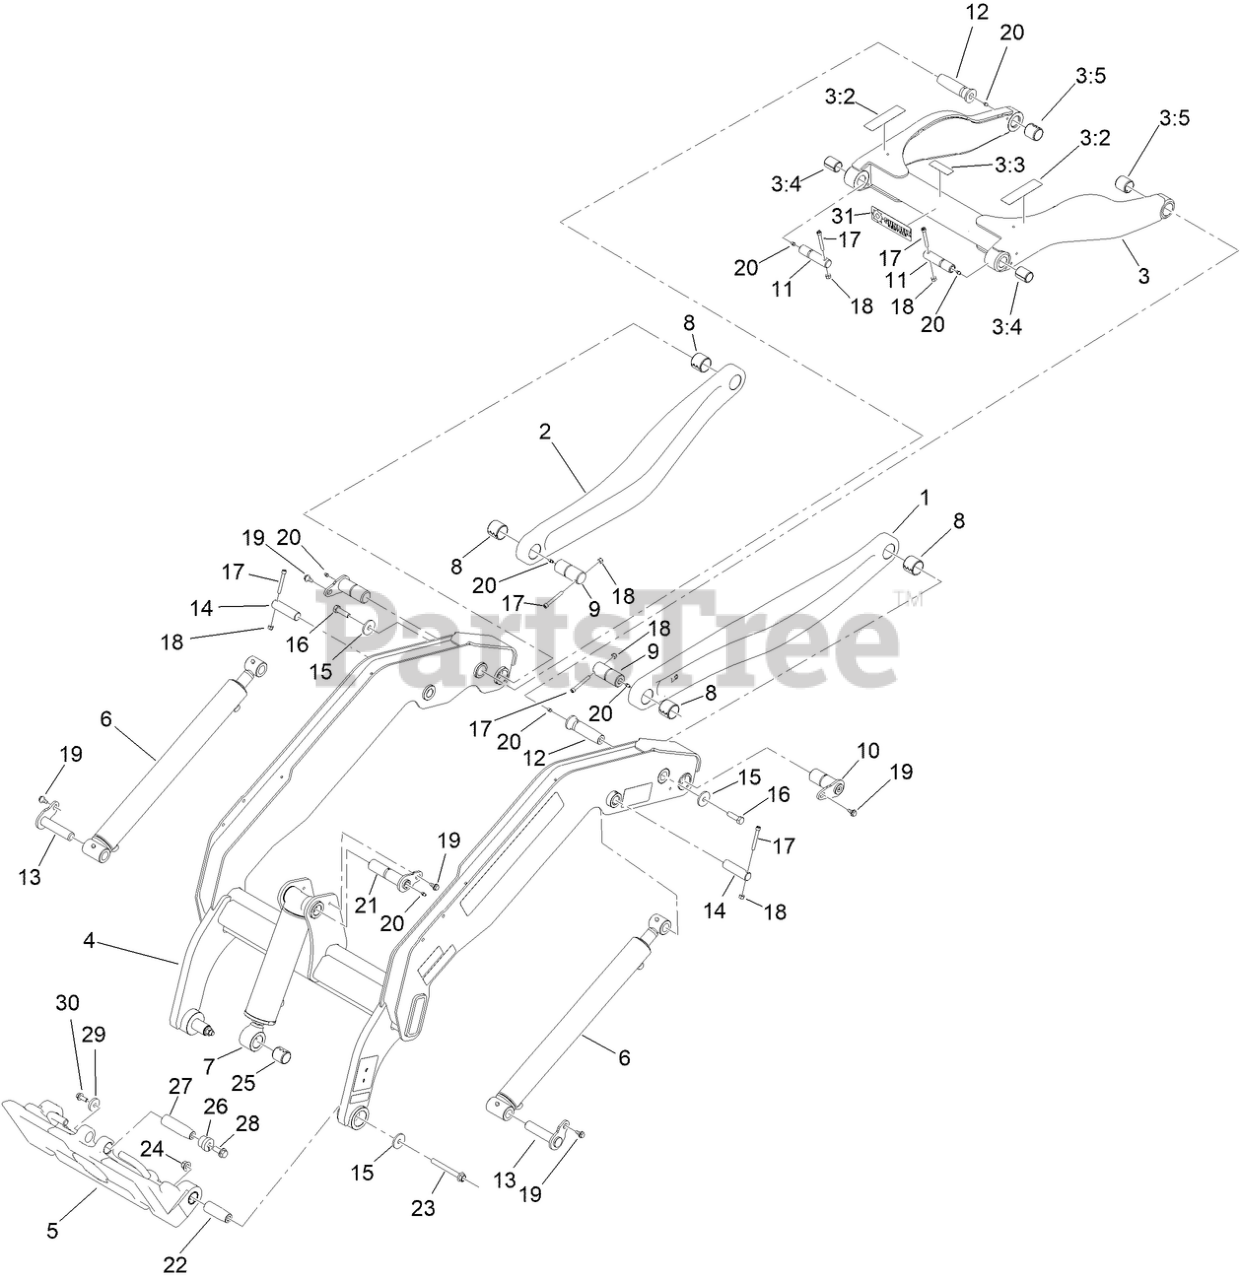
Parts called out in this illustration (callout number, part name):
1	LINK-LOWER, LH [BLK-TXT]
2	LINK-LOWER, RH [BLK-TXT]
3	UPPER LINK ASM-LOADER
3:2	DECAL-WARNING, CRUSHING
3:3	DECAL-WARNING, PINCH POINT
3:4	BUSHING-SPRING
3:5	BUSHING-SPRING
4	LOADER ARM ASM-WT
5	ATTACHMENT PLATE ASM
6	CYLINDER HYD (2.25X20.16 DOUBLE ACTION)
7	CYL-HYD
8	BUSHING-SPRING
9	PIN-ARM
10	PIN-PIVOT
11	PIN-LINK
12	PIN-TAPER
13	PIN-FLAG
14	PIN-PIVOT
15	WASHER-THRUST
16	SCREW-HH
17	SCREW-HSH
18	NUT-LOCK, NI
19	BOLT-SHOULDER
20	FITTING-GREASE
21	FLAG PIN ASM
22	PIN-LINK,TAPER
23	SCREW-HHF
24	NUT-LOCK
25	BUSHING-SPRING
26	INSERT-TAPERED
27	PIN-TAPERED
28	SCREW-HHF
29	WASHER-CLUTCH
30	SCREW-HHF
31	DECAL-SRHSW2X6
